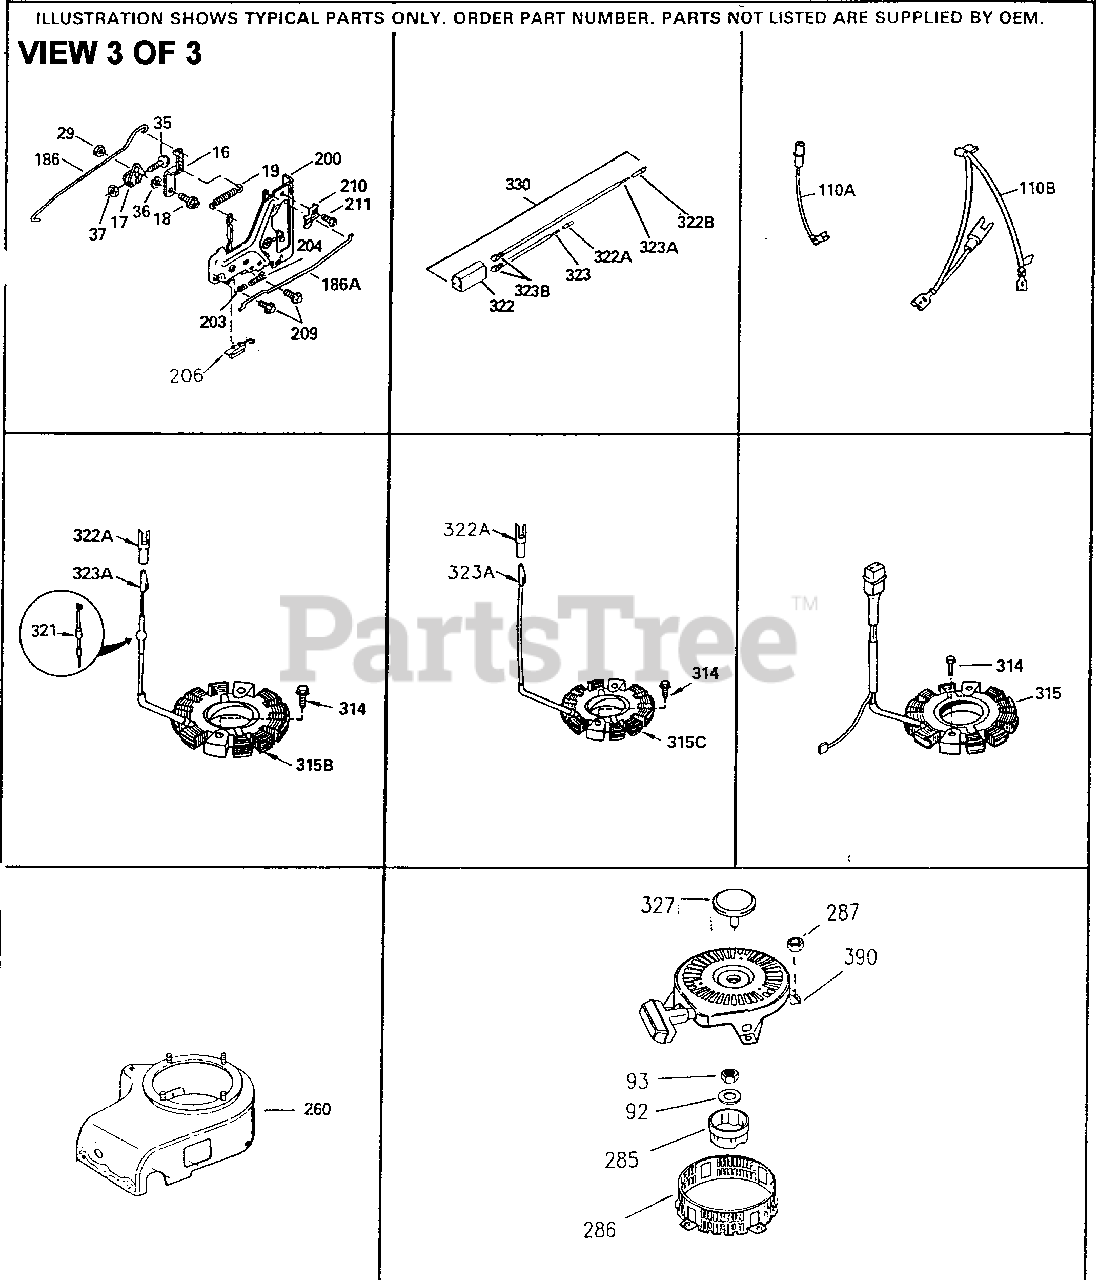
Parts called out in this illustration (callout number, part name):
16	Governor Lever (Incl. 212A)
17	Governor Lever Clamp
18	Screw, 8-32 x 5/16"
19	Extension Spring
28	Lock Nut, 8-32
35	Screw, 10-32 x 3/4"
36	Lock Washer #8
37	Lock Nut, 10-32
92	Lock Washer
93	Flywheel Nut
186	Governor Link
186A	Choke Link
200	Control Bracket (Incl. 203 & 204)
203	Compression Spring
204	Screw, 6-32 x 21/32"
209	Screw, 10-32 x 7/16"
210	Conduit Clip
211	Screw, 10-32 x 3/8"
238	Screw, 10-32 x 5-1/4"
245A	Pre-Cleaner Air Filter also available in Packaged Part #740015B
260	Blower Housing
261	Screw, T-30, 1/4-20 x 1/2"
286	Cup & Screen
308	Filler Tube Clip
308A	Fill Tube Clip
314	Screw, 1/4-20 x 3/4"
315	Alternator Coil (5 Amp DC) Incl. 322 & 323
319	Screw, 10-24 x 3/8"
320	Regulator
322	Connector Body
323	Terminal
337	Deflector
